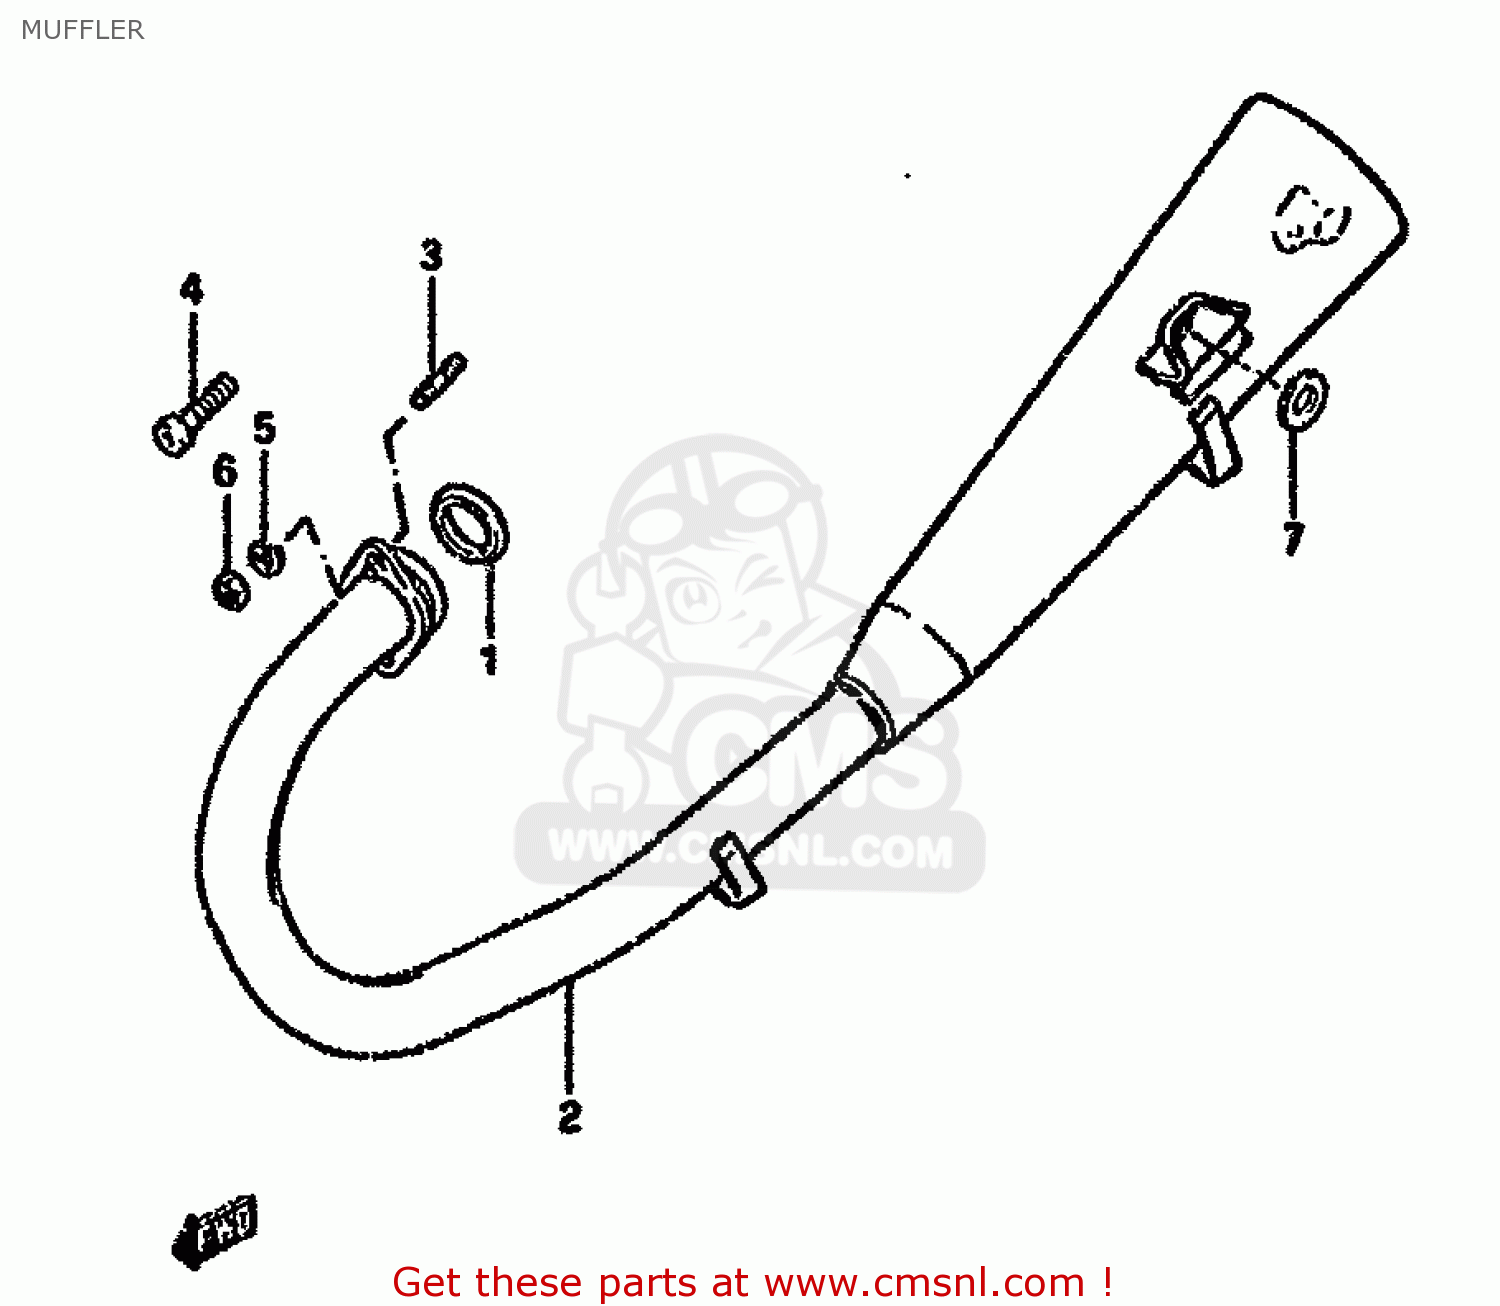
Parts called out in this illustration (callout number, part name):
1	GASKET,EXHAUST (NAS)
2	MUFFLER
3	STUD 6X20
4	BOLT, FRONT LH
5	WASHER,LOCK
6	NUT
7	WASHER
